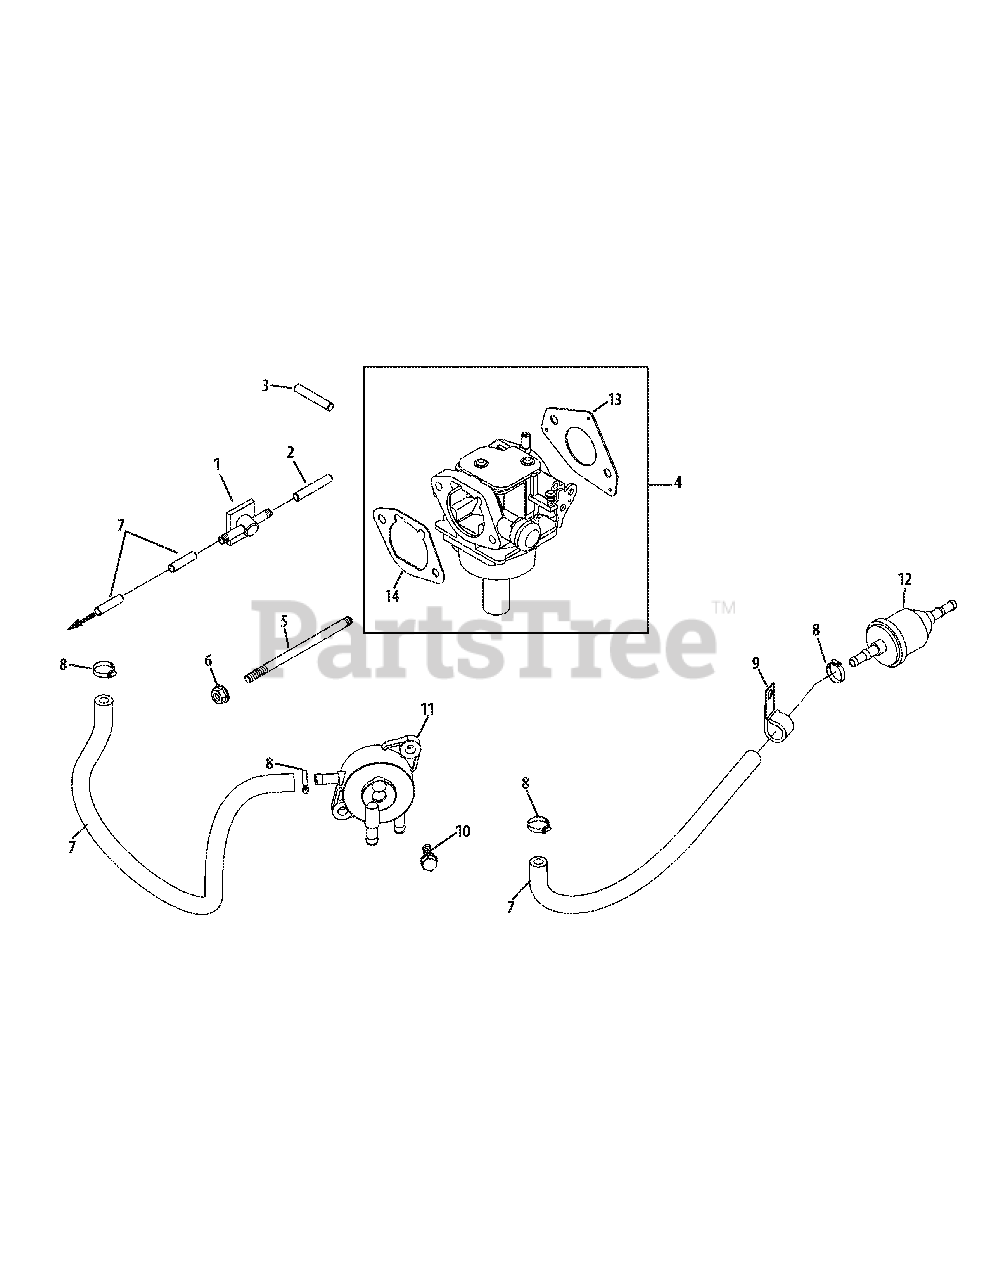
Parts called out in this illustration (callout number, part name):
1	SAI Connector
4	Carburetor Kit (Inc. #13 & 14)
5	Stud, M6 x 1.0 x 106
6	Flange Nut, M6 x 1.0
7	Fuel Line
8	Hose Clamp, 1.2
10	Screw, M6 x 1.7 x 18
13	Carburetor Gasket
14	Air Cleaner Base Gasket
